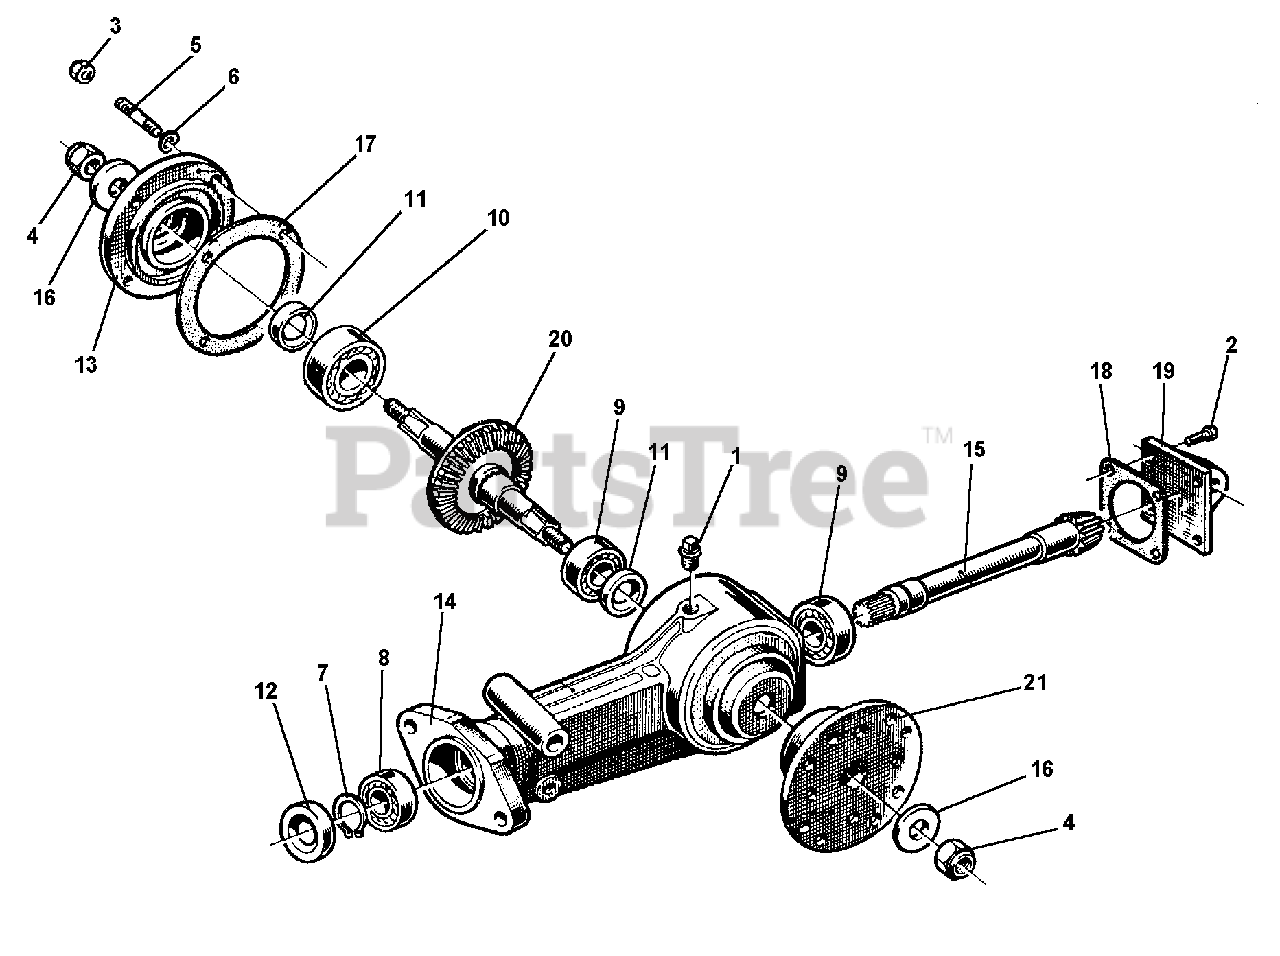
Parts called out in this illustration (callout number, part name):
2	SCREW M6 X 16
3	NUT, SELF LOCKING M 8
4	NUT, SELF LOCKING M12
5	STUD M8 X 32 X 14 X14
6	WASHER, LOCK 8.4
7	CIRCLIP EXTERNAL
8	BEARING M20 X 47 X 14
9	BEARING M20 X 47 X 14
10	BEARING M20 X 52 X15
11	OIL SEAL M20 X 35 X7
12	OIL SEAL M20 X 42 X 7
15	PINION SHAFT
16	SUPER WASHER
20	BEVELED GEAR
